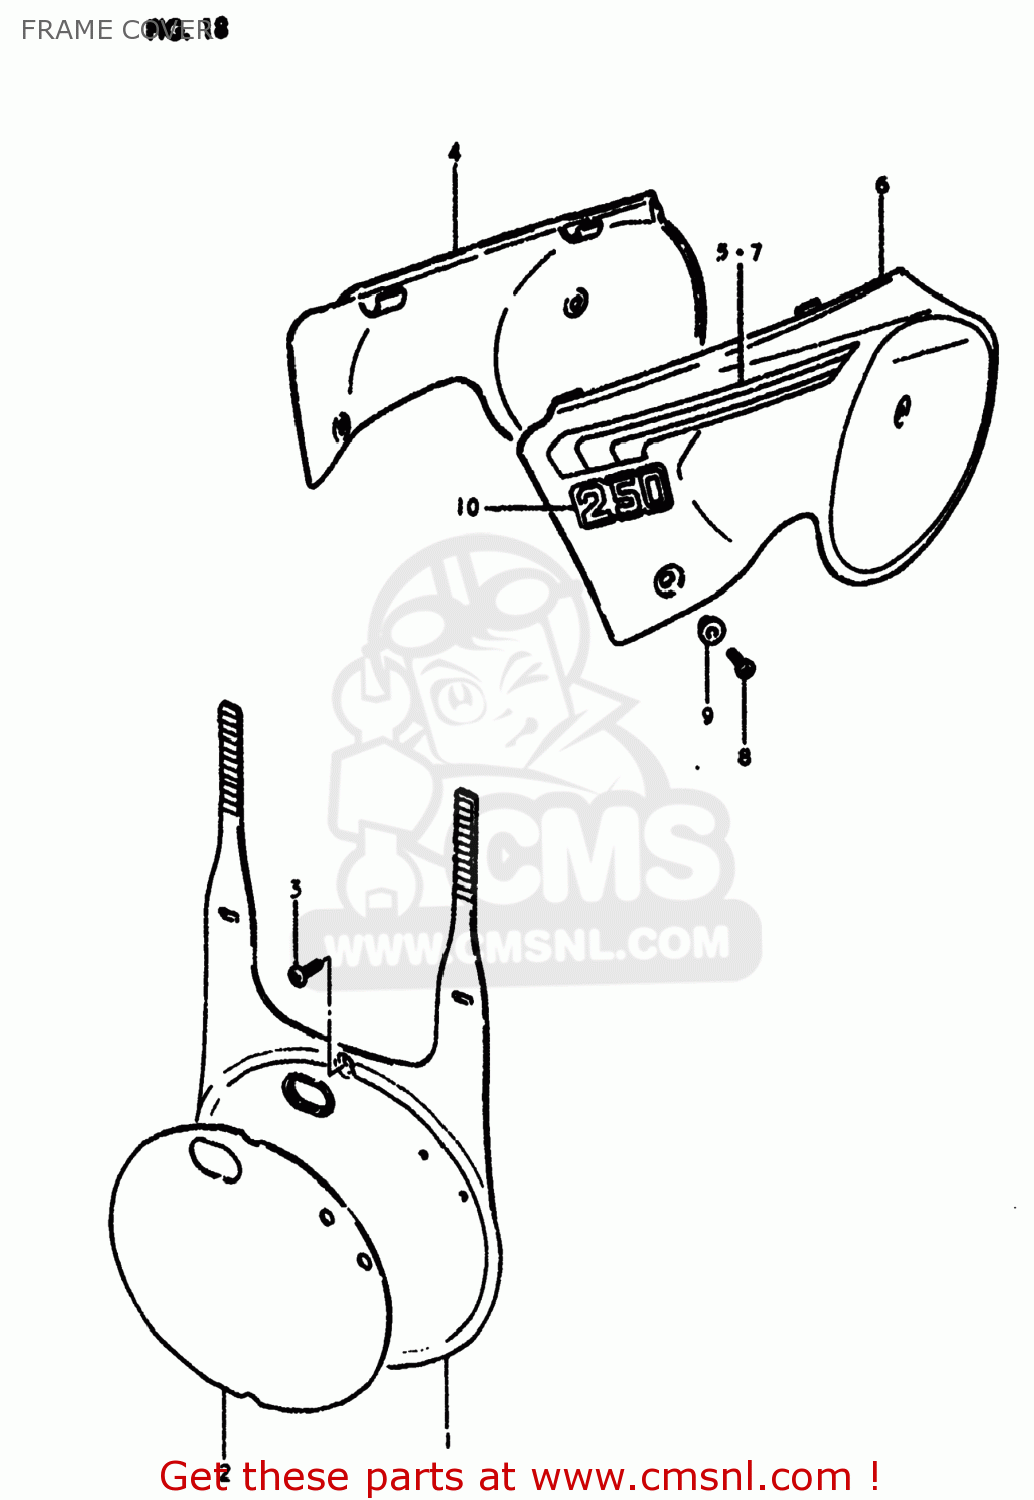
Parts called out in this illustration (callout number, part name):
1	PLATE,FR NUMBER
2	EMBLEM,FRONT NUMBER PLATE
3	(5X20) CROSS SCREW
4	COVER,FRAME,RIGHT
5	TAPE,FRAME COVER
6	COVER,FRAME,LEFT
7	TAPE,FRAME COVER
8	SCREW 6X12
9	SPACER
10	EMBLEM (250)
